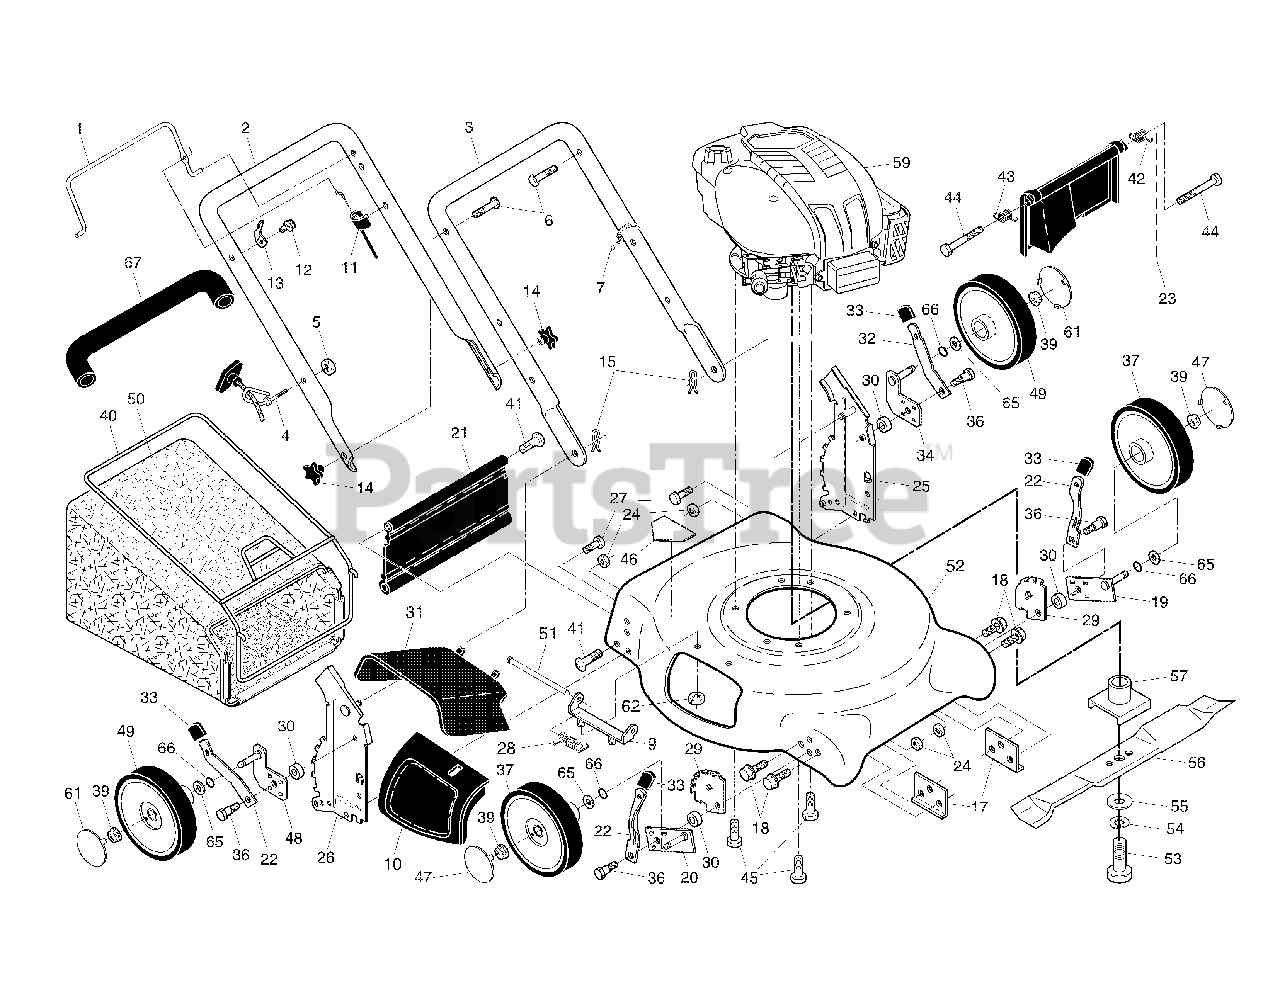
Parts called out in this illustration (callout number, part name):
1	Control Bar
2	Upper Handle
3	Lower Handle
4	Rope Guide
5	Nut, Hex 1/4-20
6	Handle Bolt
7	Wire Tie
9	Hinge Bracket
10	Mulcher Door
11	Engine Zone Control Cable
12	Hex Washer Head Screw
13	Up-Stop Bracket
14	Handle Knob
15	Hairpin Cotter
17	Support Bracket
19	Axle Arm Assembly, Front, LH
20	Axle Arm Assembly, Front, RH
21	Rear Skirt
22	Selector Spring, Front
23	Rear Door Assembly Kit
24	Locknut, Hex 5/16-18
25	Handle Bracket Assembly, LH
26	Handle Bracket Assembly, RH
27	Screw 1/4-20 x 3/8
28	Hinge Spring
29	Wheel Adjusting Bracket, Front
31	Clip-on Discharge Guard
32	Selector Spring, Rear
33	Selector Knob
34	Axle Arm Assembly, Rear, LH
36	Shoulder Bolt 5/16-18
37	Wheel Assembly, Front
39	Flanged Locknut
40	Frame, Grassbag
41	Hinge Screw
42	Spring, Rear Door, LH
43	Spring, Rear Door, RH
45	Hex Head Thread Rolling Screw 3/8-16 x 1
46	Danger Decal
47	Hubcap, Front Wheel
48	Axle Arm Assembly, Rear, RH
49	Wheel Assembly, Rear
50	Grassbag
52	Kit, Lawn Mower Housing
53	Hex Head Screw 3/8-24 x 1-3/8 Grade 8
54	Helical Lockwasher
55	Hardened Washer
57	Blade Adapter
61	Hubcap, Rear Wheel
62	Locknut, Hex 1/4-20
65	Washer, Flat 3/8
66	O-Ring
67	Grip, Foam
